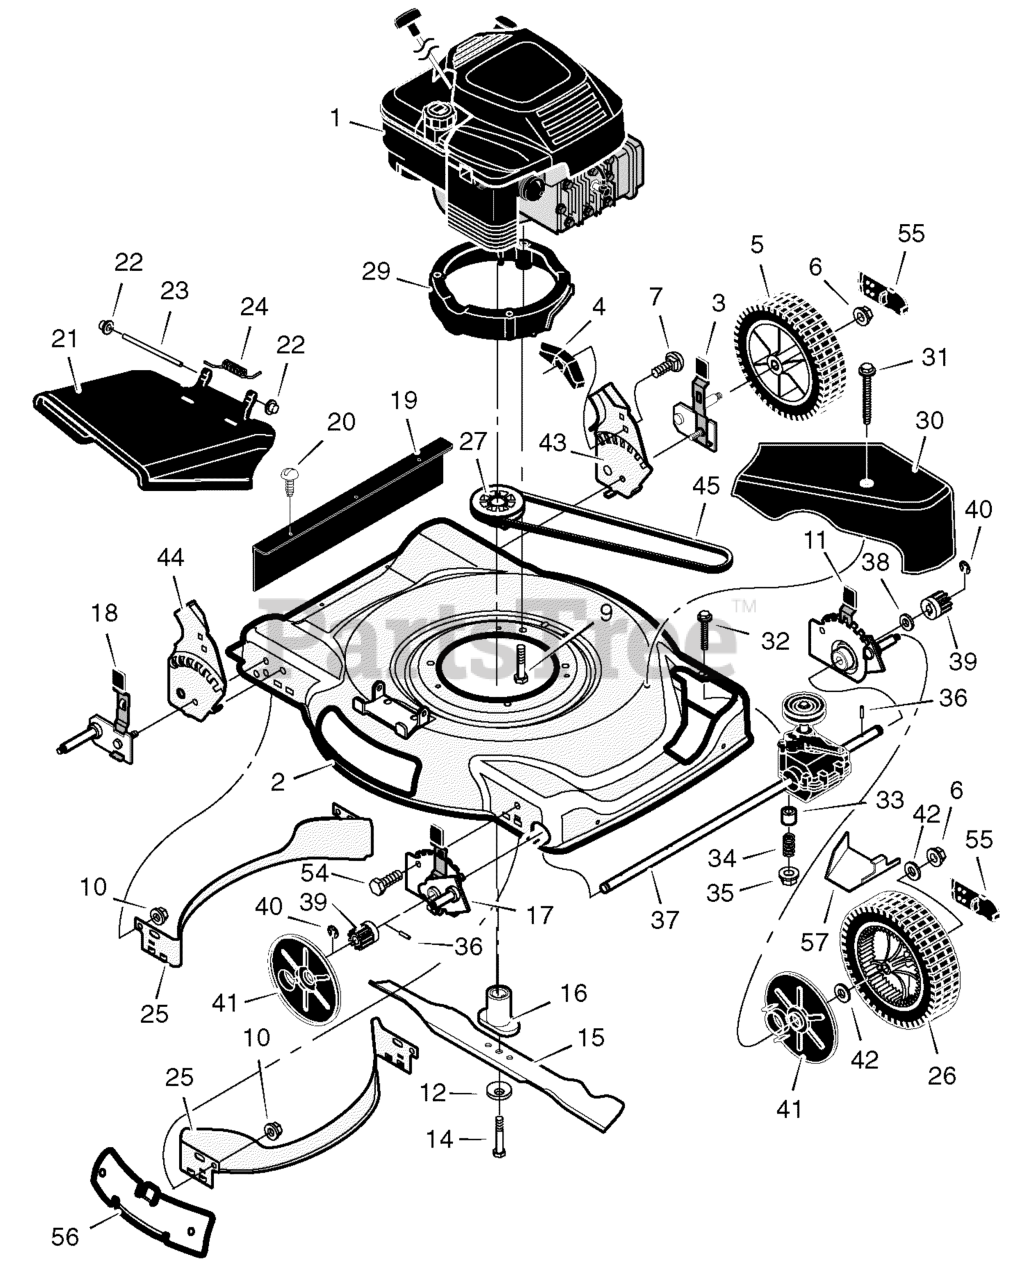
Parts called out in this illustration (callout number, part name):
1	Engine*
2	Housing
3	Height Adjuster, Left Rear
5	Wheel & Tire, Rear
6	Locknut, Flange
7	Bolt, Carriage
9	Bolt, Engine
10	Nut
11	Height Adjuster, Left Front
12	Washer, Belleville
14	Bolt, Hex
16	Adapter, Blade
17	Height Adjuster, Right Front
18	Height Adjuster, Right Rear
19	Guard, Rear
21	Deflector Chute
22	Push-On Cap
23	Pin, Pivot
24	Spring
26	Wheel & Tire, Drive
29	Base, Engine
30	Cover, Belt (Black)
30	Cover, Belt (Gray)
33	Spacer
34	Spring
35	Nut
36	Pin, Drive
37	Transmission
38	Washer
39	Gear, Pinion
40	E-Ring
41	Cover, Dust
42	Washer
43	Bracket, Left Handle
44	Bracket, Right Handle
45	Belt, B & S
54	Bolt
55	Hub Cap
56	Plate, Mulcher
57	Cover, Transmission
